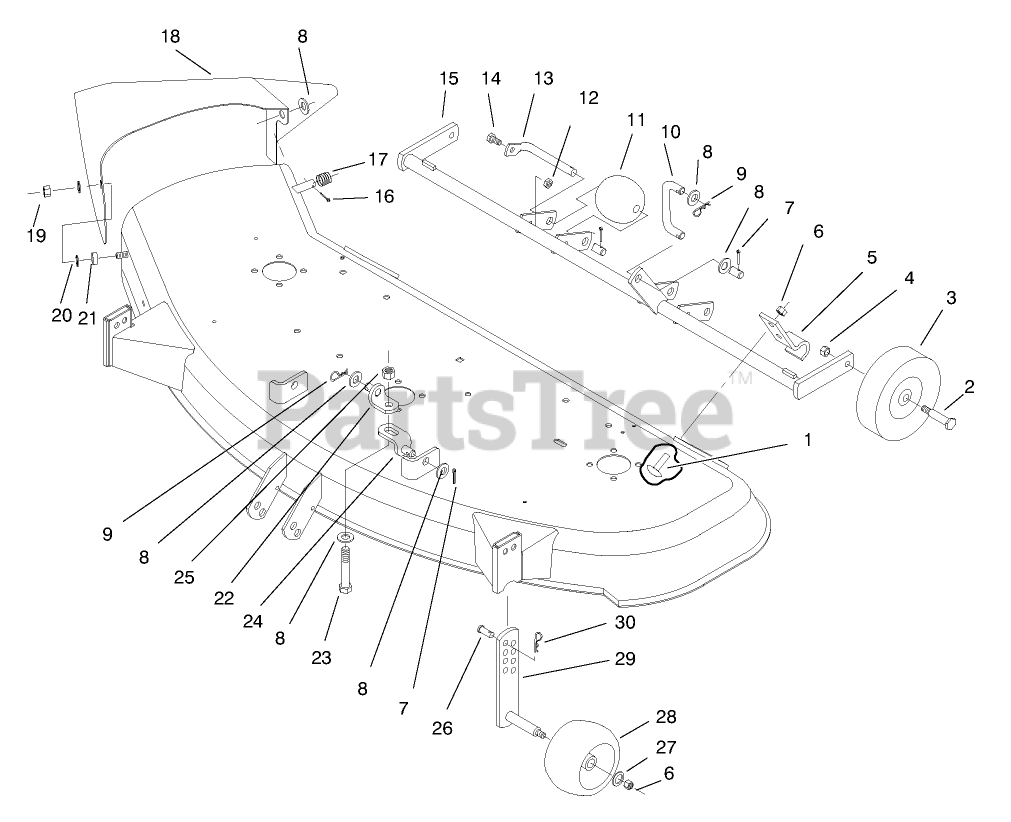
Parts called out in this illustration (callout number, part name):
1	BOLT-CARR
2	BOLT-SHOULDER
3	WHEEL
4	NUT-HEX
5	BRACKET-PIVOT
6	NUT-LOCK, NI
7	PIN-COTTER
8	WASHER-FLAT
9	PIN-COTTER, HAIR
10	LINK-REAR
11	ROLLER
12	NUT-LOCK, NI
13	SHAFT-ROLLER
14	SCREW-HH
15	SUPPORT-GAGE WHEEL
16	PIN-COTTER
17	SPRING-DEFLECTOR
18	Chute / Decal Asm
19	NUT-HJ
20	WASHER
21	BUSHING-PIVOT
22	BRACKET-LIFT, UPPER
23	SCREW-HH
24	BRACKET-LIFT, LOWER
25	NUT-JAM
26	PIN-CLEVIS
27	WASHER-FLAT
28	WHEEL-GAGE
29	GAGE-WHEEL
30	PIN-HAIR
